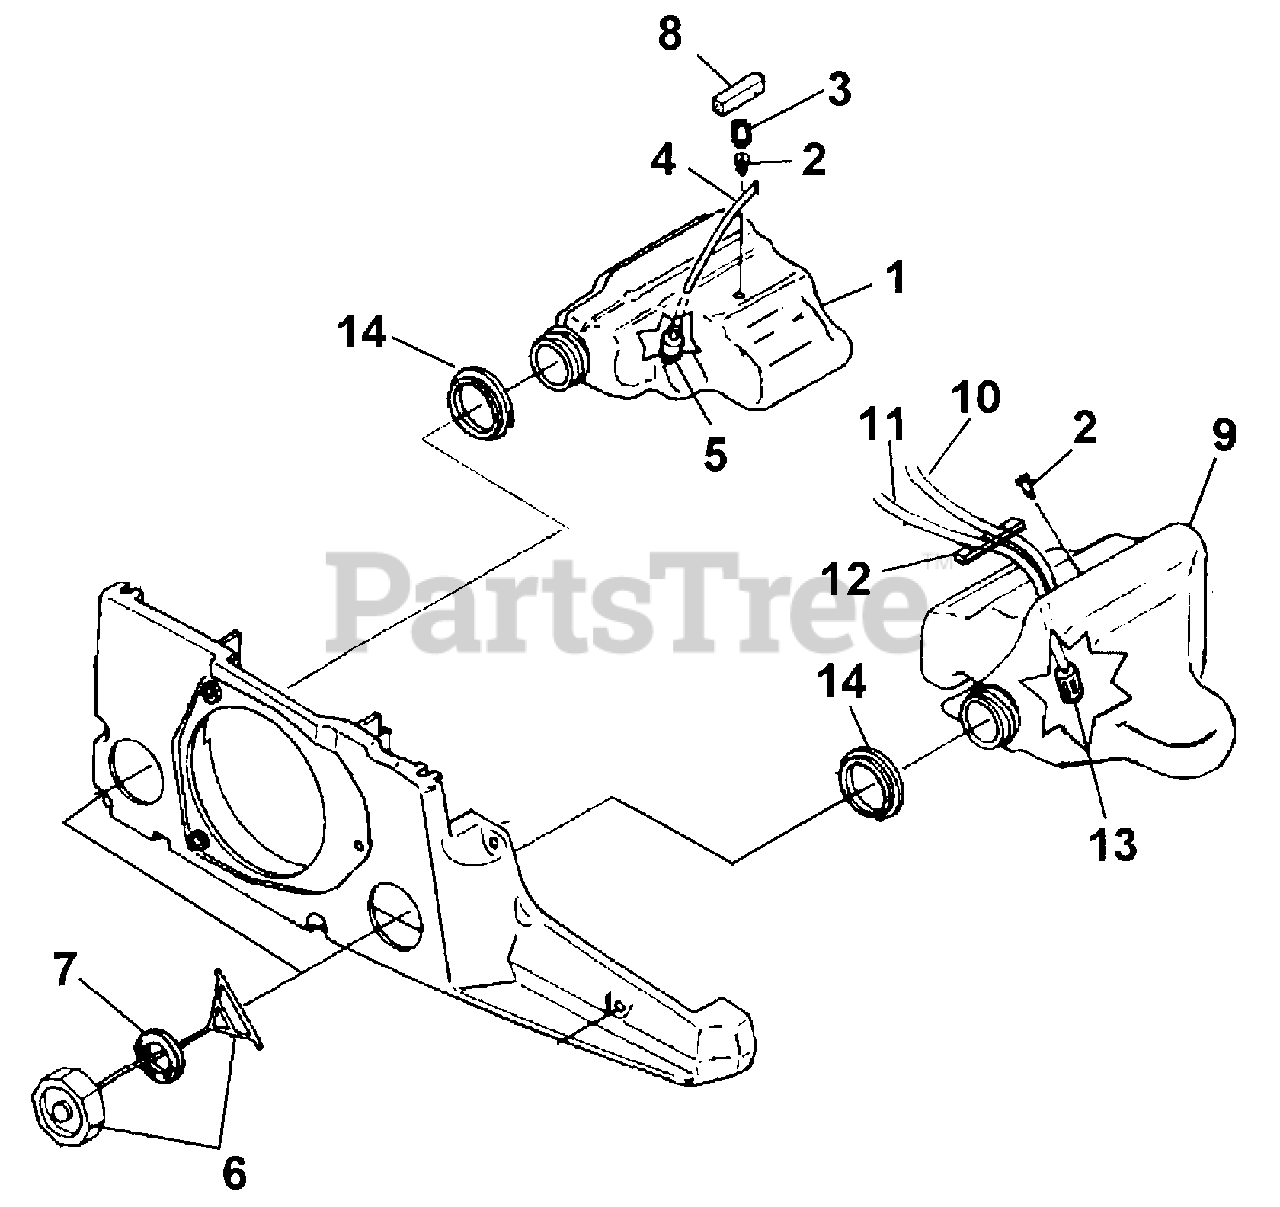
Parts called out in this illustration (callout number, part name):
1	OIL TANK ASSY
2	VALVE-Check
2	VALVE- Check
3	PIN-Spirol
4	TUBING- Rubber (7 1/4")
5	FILTER- Oil
6	CAP- Tank (w/Retainer)
7	GASKET Fuel Cap
8	FILTER- Oil Tank Valve
9	FUEL TANK ASSY
10	TUBING-Rubber (5 1/4")
11	TUBING- Rubber (9")
12	FILTER- Foam
13	FILTER- Fuel
14	SAWDUST SEAL
